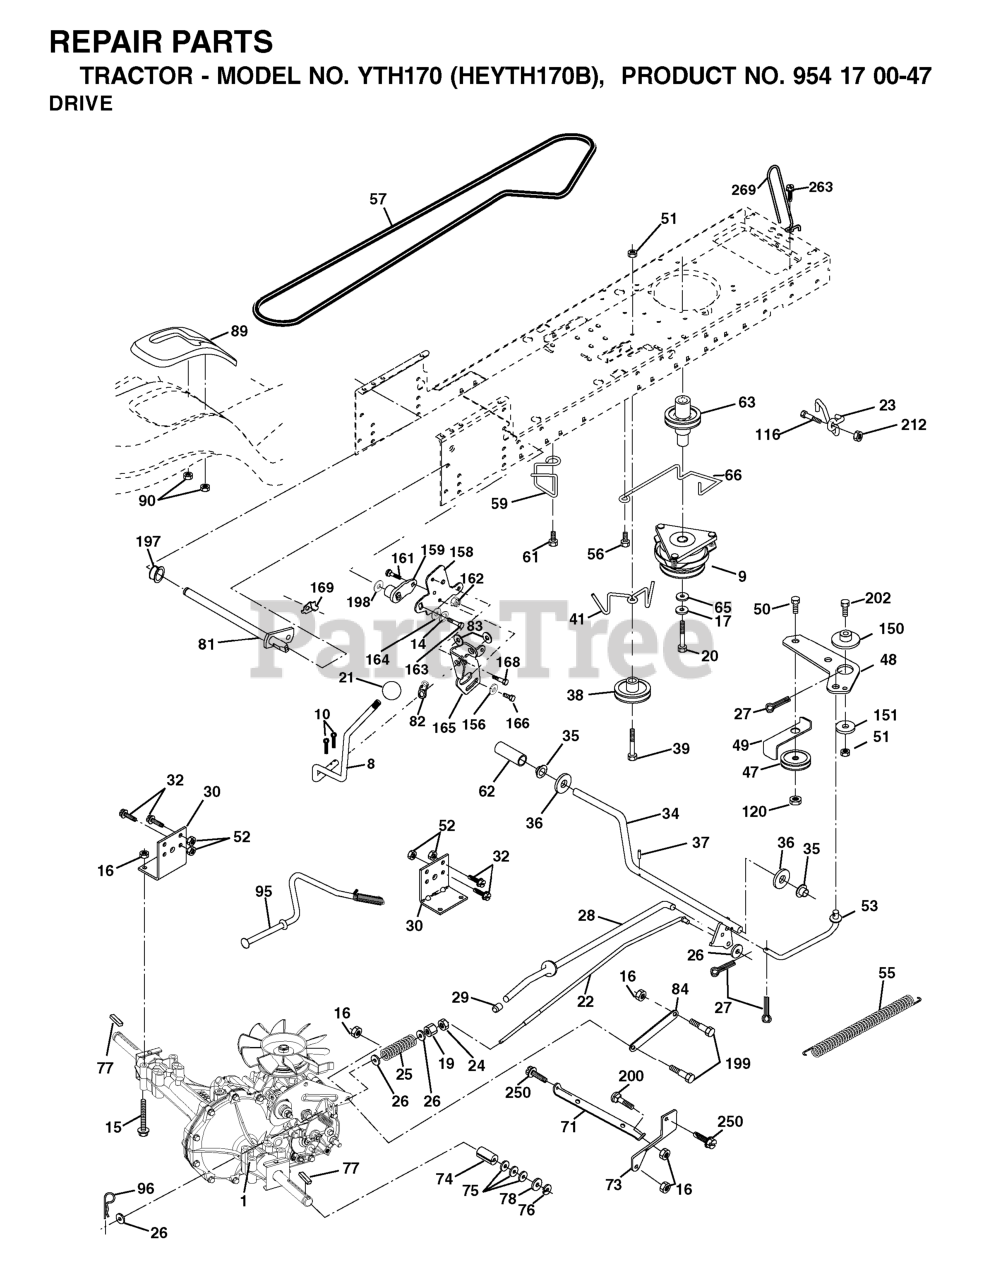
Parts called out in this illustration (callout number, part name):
8	ROD SHIFT FENDER ADJUST STLT
10	PIN COTTER
14	LOCKWASHER
15	BOLT HEX 5/16-18 GR 5
16	NUT.71038.31-18.HEX.NYLOCK
19	NUT
20	BOLT HEX 7/16-20X4-1/4"
21	KNOB.DUCKHEAD.1/2
22	ROD BRAKE HYDRO
23	BRKT ASM MTNG
24	NUT
25	SPRING ROD LT
26	WASHER
27	COTTER PIN
28	ROD, PARKING BRAKE
29	PLUNGER CAP
30	BRKT, TRNSXLE MNT 20"
32	BOLT
34	SHAFT, FOOT PEDAL
35	BEARING.NYLON
37	DRIVE PIN
38	PULLEY IDLER COMPOSITE
39	BOLT
41	KEEPER, BELT IDLER
47	IDLER PULLEY
48	BELLCRANK, CLUTCH
49	RETAIN BELT
50	BOLT.3/8-16X1.50
52	LOCKNUT
53	LINK, CLUTCH LT
55	SPRING, RETURN LT
56	SCREW.3/8-16
57	DRIVE BELT, LTH & YTH TRACTORS
59	KEEPER, BELT CENTER
61	SCREW 3/8-16X.875
62	COVER, PEDAL (1 2)
63	PULLEY- ENGINE
65	LOCKWASHER
66	KEEPER BELT ENGINE
71	STRAP TORQUE LH HYDRO
73	STRAP TORQUE RH HYDRO
74	SPACER AXLE
77	SQUARE KEY
81	SHAFT ASM CROSS TAPERED
82	SHIFT SPRING
83	WASHER
84	LINK TRANSAXLE
89	SHIFT CONSOLE
90	NUT.PUSH.3/16
95	CONTROL ASM. BYPASS HYDRO
96	RETAINER M
116	BOLT D
120	NUT LOCK FLG 3/8-16 UNC
150	SPACER, RETAINER
151	WASHER 12/32X2X10GA
156	WASHER.SRRTD.5/16
158	BRACKET
159	HUB
161	BOLT
162	NUT.CROWNLOCK.1/4
164	Washer 5/8 x .281 x 10 Ga.
165	RP BRACKET
168	BOLT.SHOULDER.5/16-18X
169	PLATE.FASTENING.CROSS.SHAFT
197	NYLINER SNAP 5/8" ID
198	WASHER.NYL.7/8IDX.105"HYD CR
199	BOLT SHOULDER 5/16-18 UNC
212	NUT
250	SCREW 3/8-16X3/4
263	SCREW, 3/8-16X3/4
269	GUARD MUFFLER
